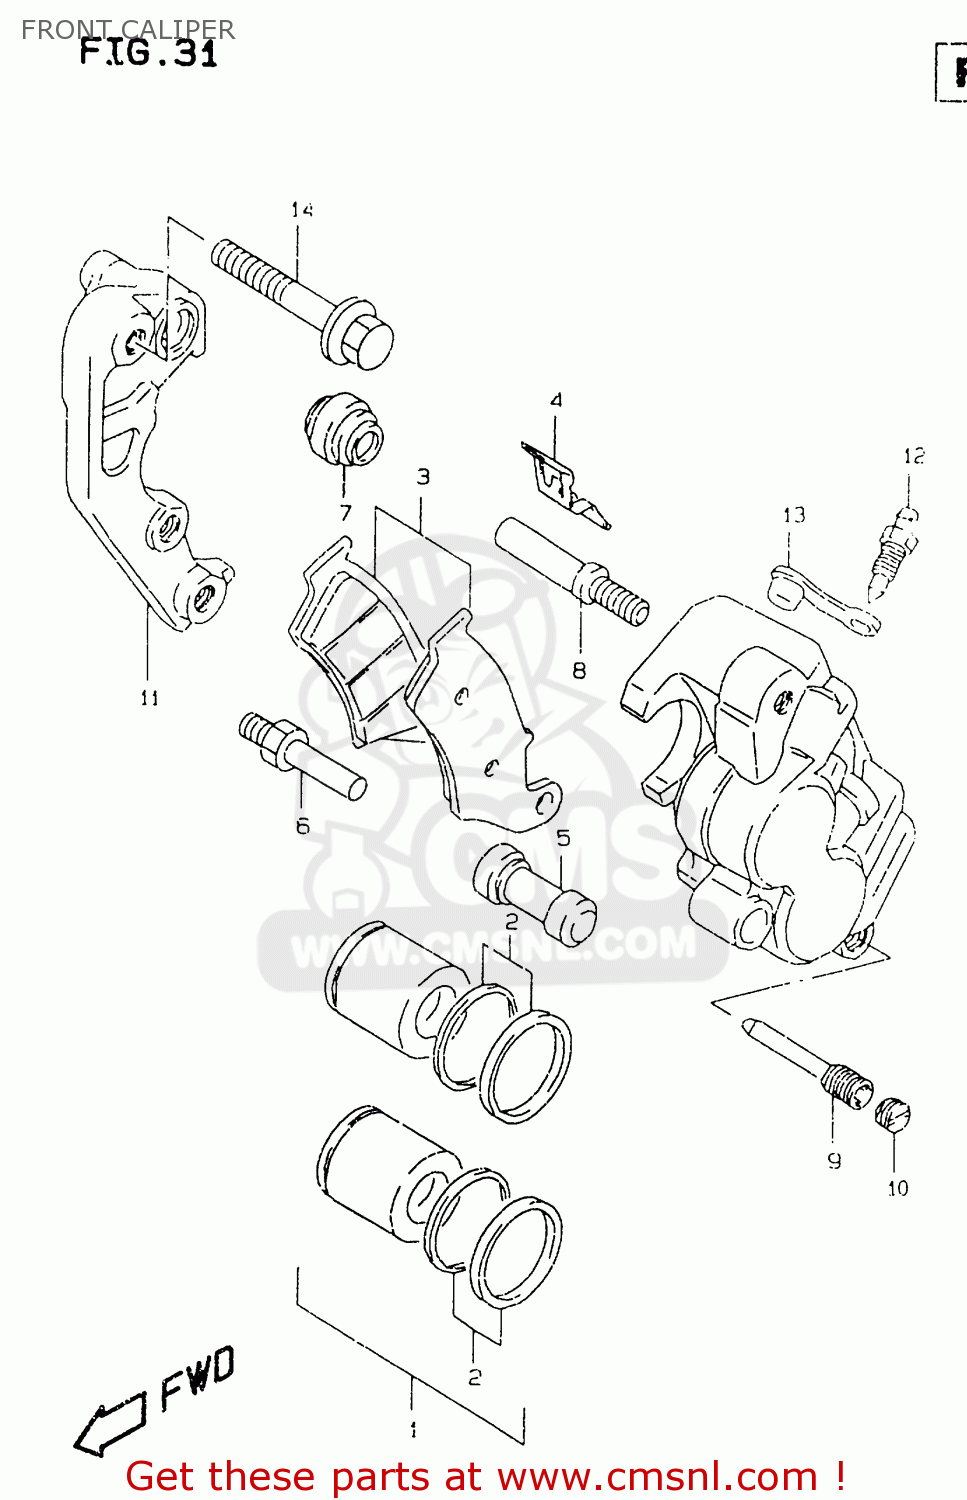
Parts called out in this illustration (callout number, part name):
1	PISTON SET
2	SEAL SET,PISTON
3	PAD SET (NAS)
4	SPRING,PAD
5	BOOT
6	PIN,BOLT
7	BOOT
8	PIN
9	PIN,HANGER
10	PLUG,PIN
11	BRACKET
12	BLEEDER
13	CAP,BLEEDER
14	BOLT(8X40)
